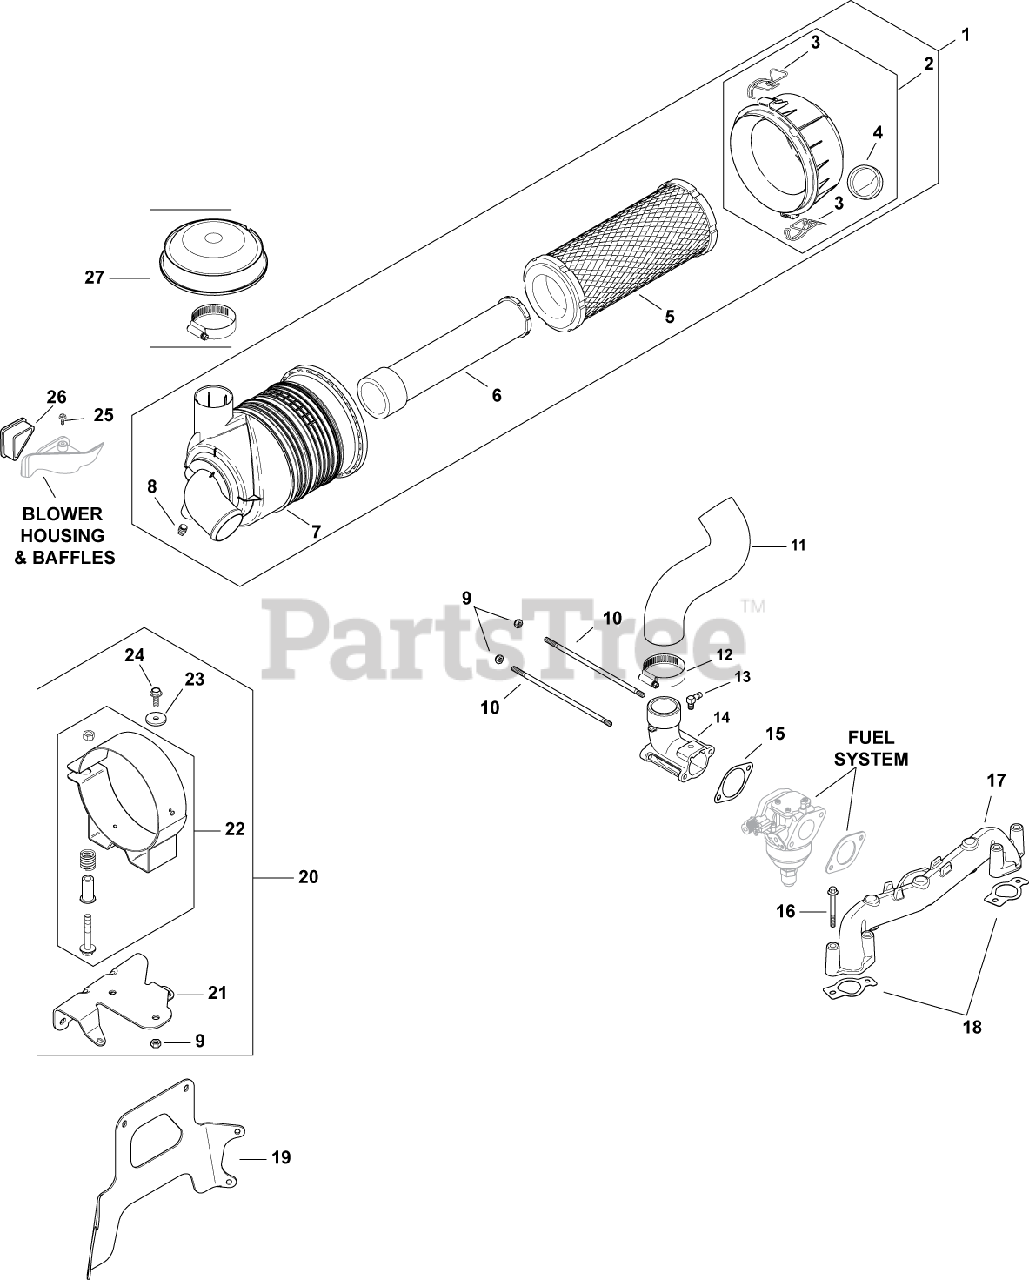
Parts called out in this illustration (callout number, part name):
1	AIR CLNR, CANISTER-USE 25 048 17-S
2	COVER ASSEMBLY, AIR CLEANER
3	CLIP - USE 62 154 07-S
4	VALVE, DUST EJECTOR
5	ELEMENT, AIR FILTER - PRIMARY
6	ELEMENT, AIR FILTER - SAFETY
7	HOUSING, HD AIR CLEANER
8	PLUG, PIPE
9	NUT, LOCK M6X1.0
10	STUD, M6X1.0X180
11	HOSE, AIR CLEANER
12	CLAMP, HOSE
13	CONNECTOR, HOSE
14	ELBOW, AIR CLEANER
15	GASKET, AIR CLEANER BASE
16	SCREW, FLG M6X1.0X55
17	MANIFOLD, INTAKE
18	GASKET, INTAKE MANIFOLD USE 24 041 79-S
19	BRACKET, MAIN SUPPORT-USE 24 126 185-S
20	BRACKET, AIR CLEANER -USE 24 126 186-S
21	BRACKET, AIR CLEANER-USE 24 126 184-S
22	BRACKET, AIR CLEANER-USE 24 126 191-S
23	WASHER, FLAT 1/4" (O.D. 1")
24	SCREW, FLG M6X1.0X16
25	SCREW, WSH HD TAP #8-18X1/2"
26	COVER, BLOWER HOUSING USE 24 096 160-S
27	HOOD, AIR CLEANER (5.25)-USE 25 324 04-S
